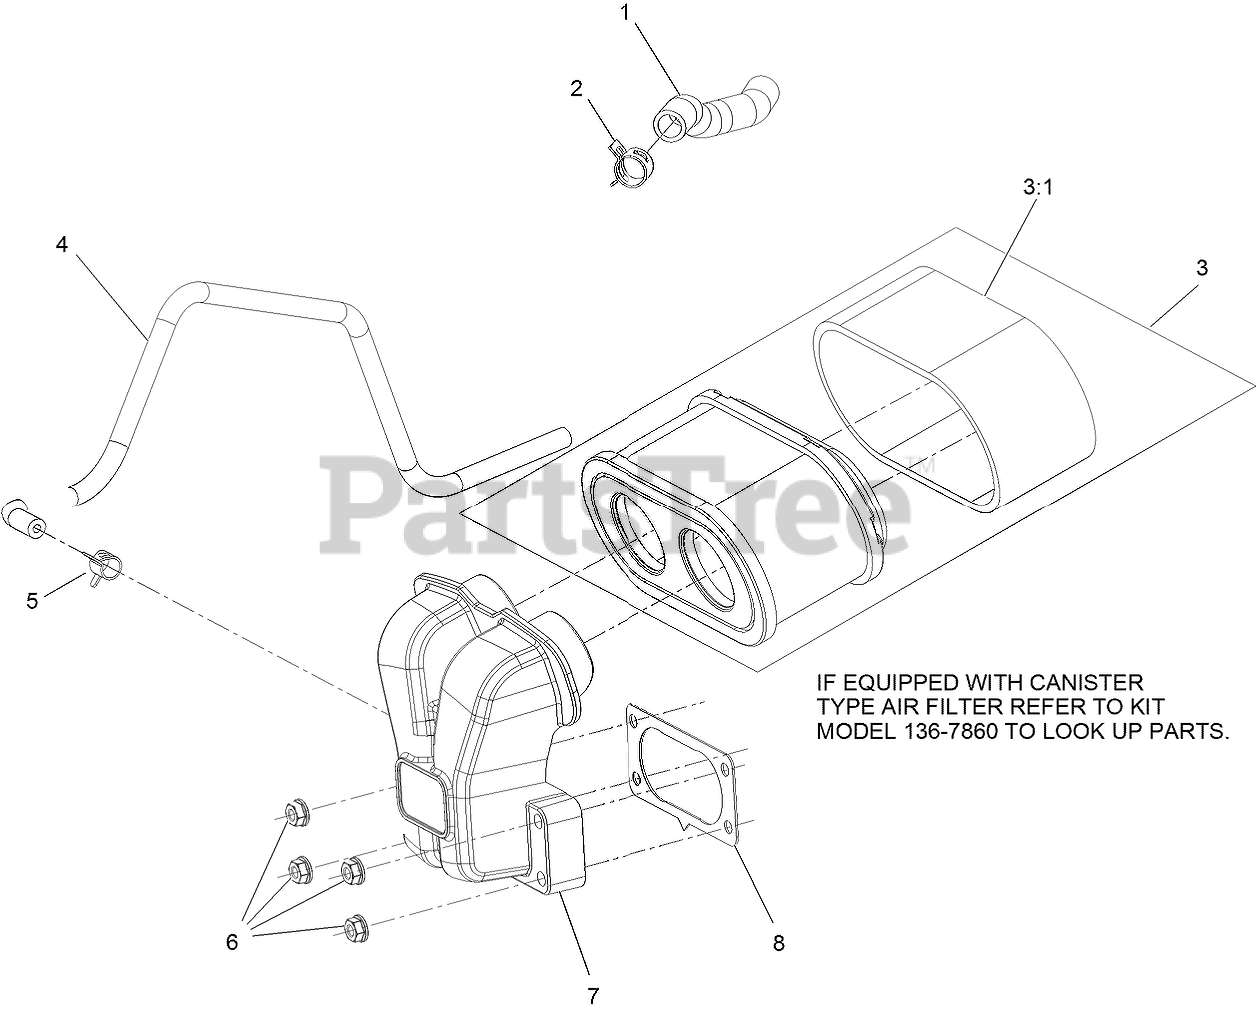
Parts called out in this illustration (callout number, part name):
1	TUBE-BREATHER
2	CLAMP-HOSE
3	AIR FILTER KIT
3:1	PREFILTER
4	HOSE-FUEL
5	CLAMP-HOSE
6	NUT-FLANGE
7	MANIFOLD-FILTER, AIR
8	GASKET-CARBURETOR
